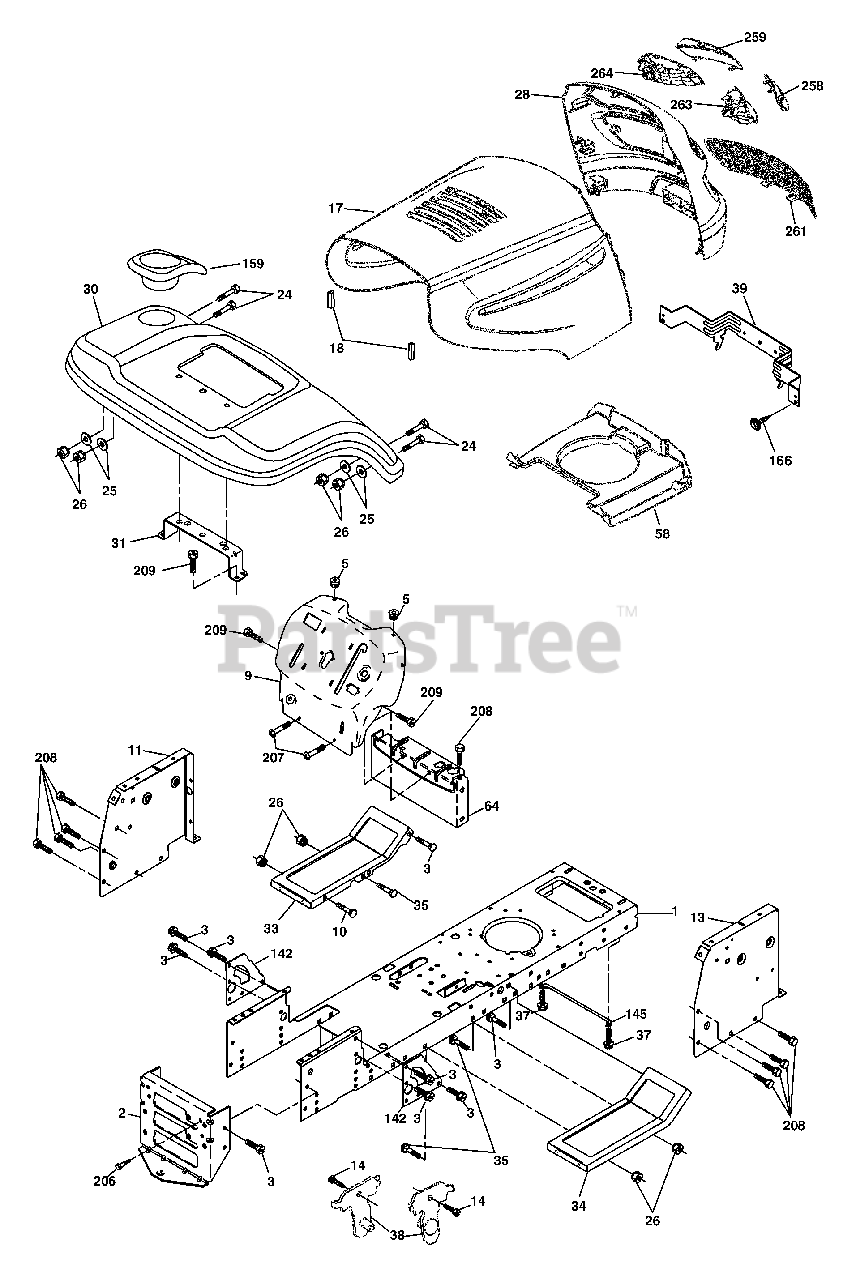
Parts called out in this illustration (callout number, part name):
1	Chassis
2	Drawbar
3	Screw 3/8-16 x 3/4
5	Bumper Hood/Dash
9	Dash
10	Bolt Rd Hd Sqnk. 3/8-16 Unc x 1
11	Panel Asm. Dash Lh
12	Clip Tinnerman Grile P/L
13	Panel Dash Rh
14	Screw Thdrol 3/8-16 x 1/2
17	Hood
18	Bumper Hood
24	Bolt Fin Hex 3/8-16 Unc x 1 Gr. 5
25	Washer 13/32 x 13/16 x 12 Ga.
26	Nut Lock Hex w/Insert 3/8-16 Unc
28	Grill/Lens Asm
30	Fender Asm
31	Bracket Fender
33	Footrest LH
34	Footrest RH
35	Bolt Rd Hd Sht. Sqnk. 3/8-16 x 3/4
37	Screw Thdrol 5/16-18 x 1/2 Tyt
38	Bracket Asm. Pivot Mower Rear
39	Bracket Pivot
58	Air Duct
64	Dash Lower
142	Plate Reinforcement
145	Rod Pivot Chassis/Hood
159	Cupholder
166	Screw #13-16 x 3/4
206	Bolt shoulder 5/16-18
207	Screw Thdrol 5/16-18 x 1/2
208	Screw Thdrol 3/8-16 x 1/2
209	Screw 3/8-16 x 3/4
258	Lens Grille RH
259	Lens Grille LH
263	Bezel Grille LH
264	Bezel Grille RH
